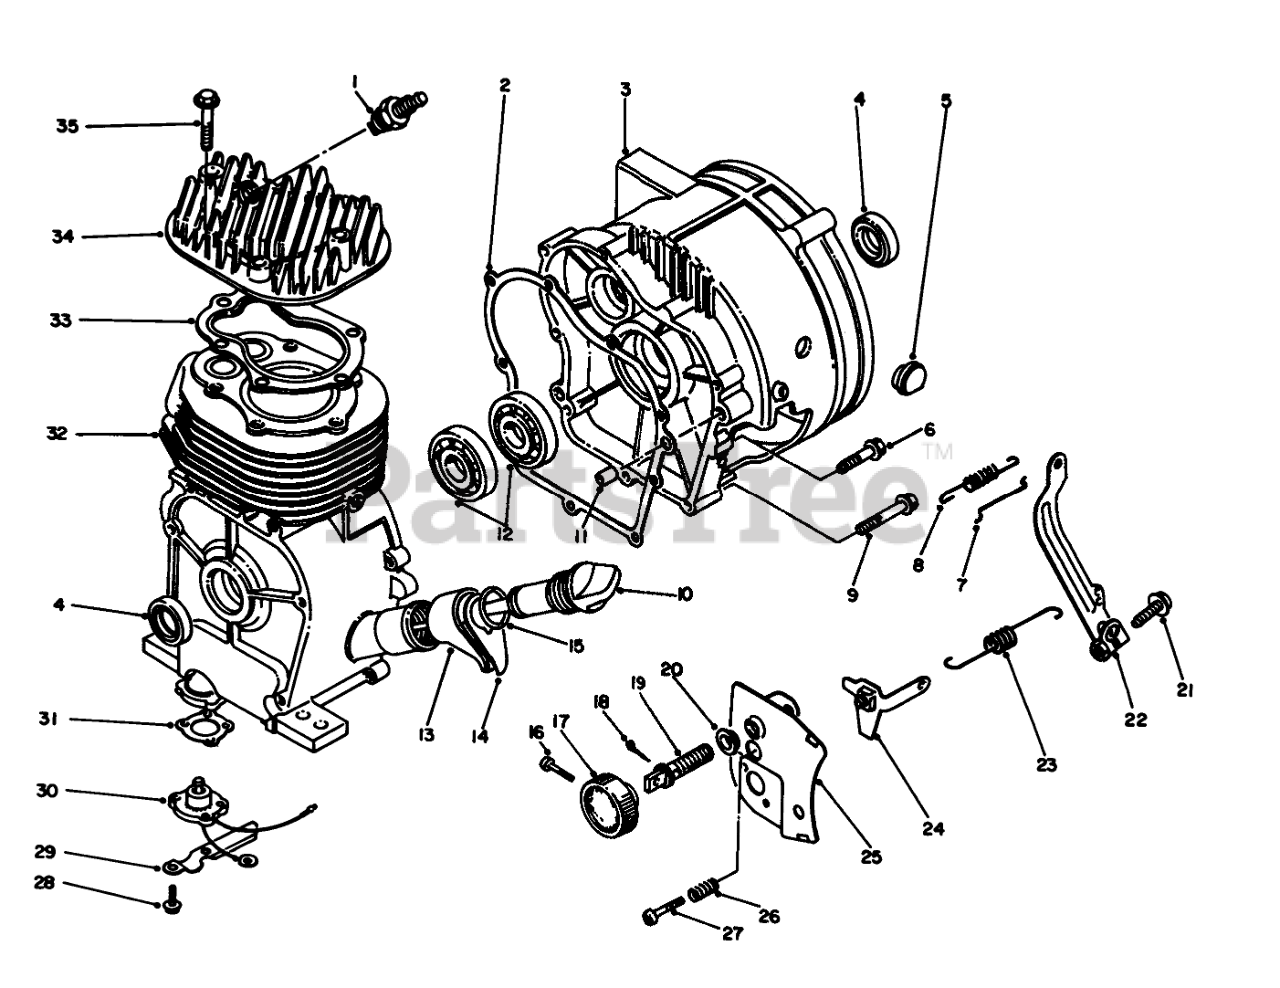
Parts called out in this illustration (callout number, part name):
1	SPARK PLUG
2	Gasket-Crankcase
3	Cover-Crankcase Side
4	OIL SEAL
5	Cap-Cover
7	Rod-Carburetor
8	SPRING
10	Gauge-Oil Level
12	Bearing
13	Plate-Oil Guide
14	Cover-Plate
15	O-RING
16	Screw
17	Knob-Throttle Control
18	Cotter Pin
19	SHAFT
20	Bushing
22	Lever-Control
23	Spring
24	Hook-Spring
25	Bracket-Throttle Control
26	Spring-Limit
27	SCREW
29	Plate-Guard
30	Sensor
31	GASKET
32	Cylinder Assembly
33	GASKET
34	Cylinder Head
